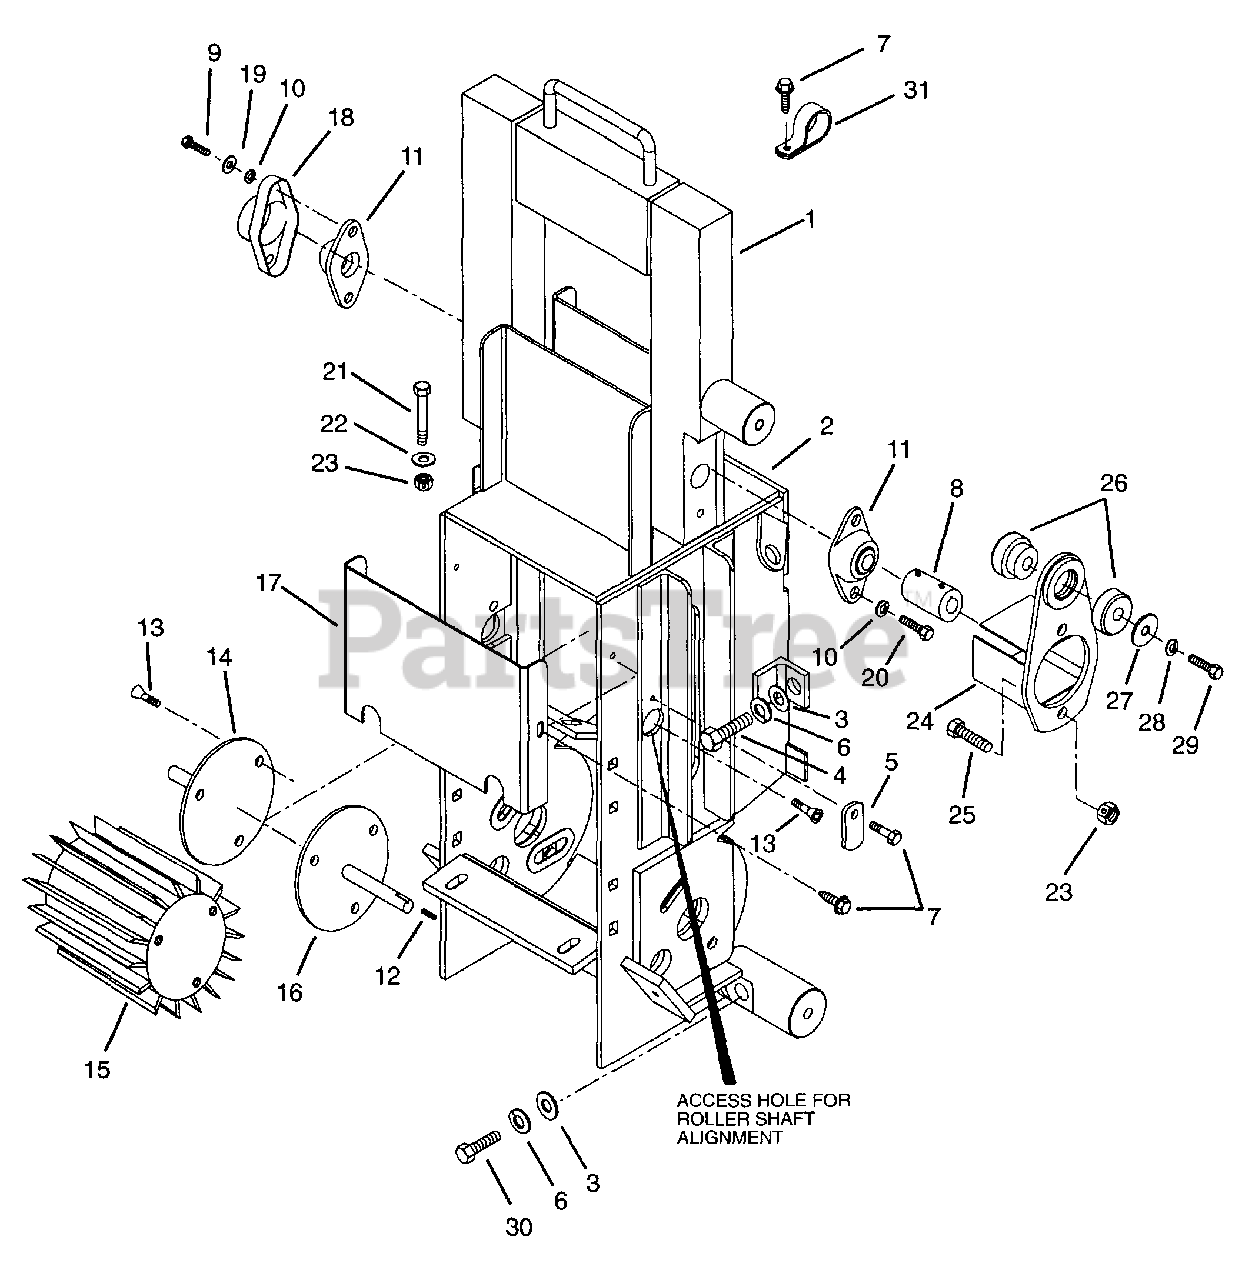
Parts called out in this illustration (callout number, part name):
1	Saddle-Weldment Assembly
2	Feed Box Weldment
3	Washer-Flat-Steel .531 x 1.06 x .095
4	Bolt-Hex .50-13 x 1.00 Grade 5
5	Enclosure
6	Washer-Lock .50 x .125
7	Screw-Tapping .25-20 x .50 Hex Washer Head
9	Bolt-Hex .44-14 x 1.50 Grade 5
10	Washer-Locking .44 x .109
11	Bearing Flange
12	Key-Square
13	Bolt-Flat Socket Head .50-13 x 1.0
14	Roller Shaft - Left
16	Roller Shaft - Right
17	Cover-Feed Box
18	Cover-Bearing Feed Roll
19	Washer-Flat-Steel .505 x 1.00 x .062
20	Bolt-Hex .44-14 x 1.25 Grade 5
21	Bolt-Hex .50-13 x 2.00 Grade 5
22	Washer-Flat-Steel .531 x 1.06 x .095
23	Nut-Locking-Center .50-13
24	Torque Arm Weldment
25	Bolt-Hex .50-13 x 1.50 Grade 5
26	Rubber Bushings
27	Washer-Flat-Steel .50 x .25 x .13
28	Washer-Locking .50 x .125
29	Bolt-Hex .50-13 x 3.00 Grade 5
30	Bolt-Hex .50-13 x 2.75 Grade 5
